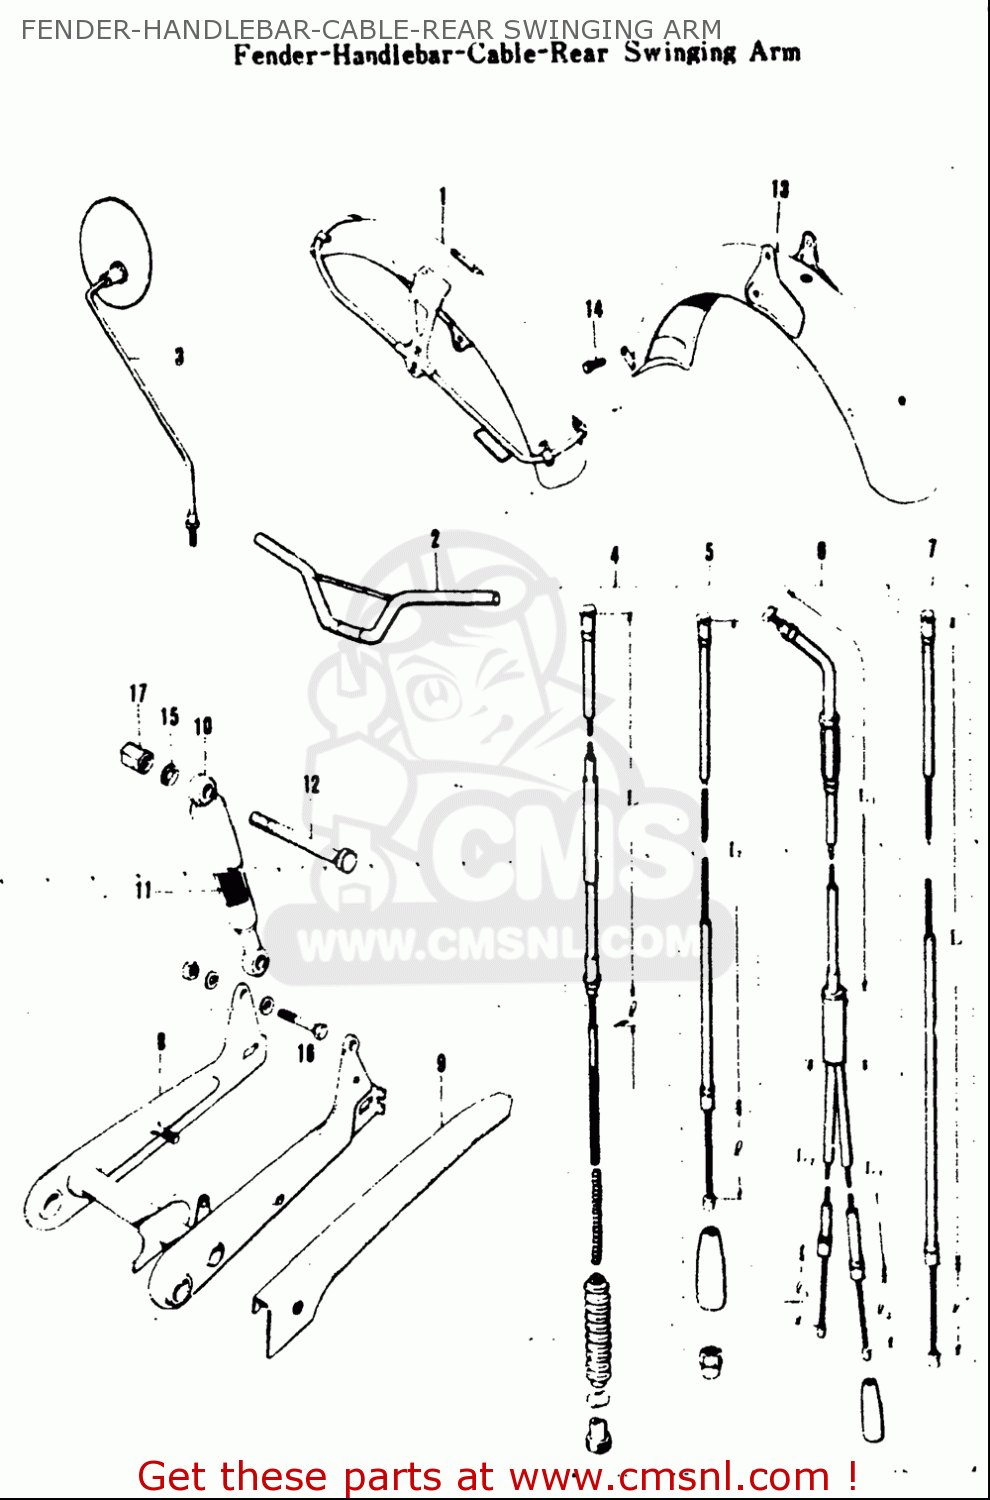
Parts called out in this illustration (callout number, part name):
6	CABLE ASSEMBLY,THROTTLE
7	CABLE,STARTER
12	SHAFT,REAR SHOCK ABSORBER
15	WASHER
16	BOLT(10X43)
